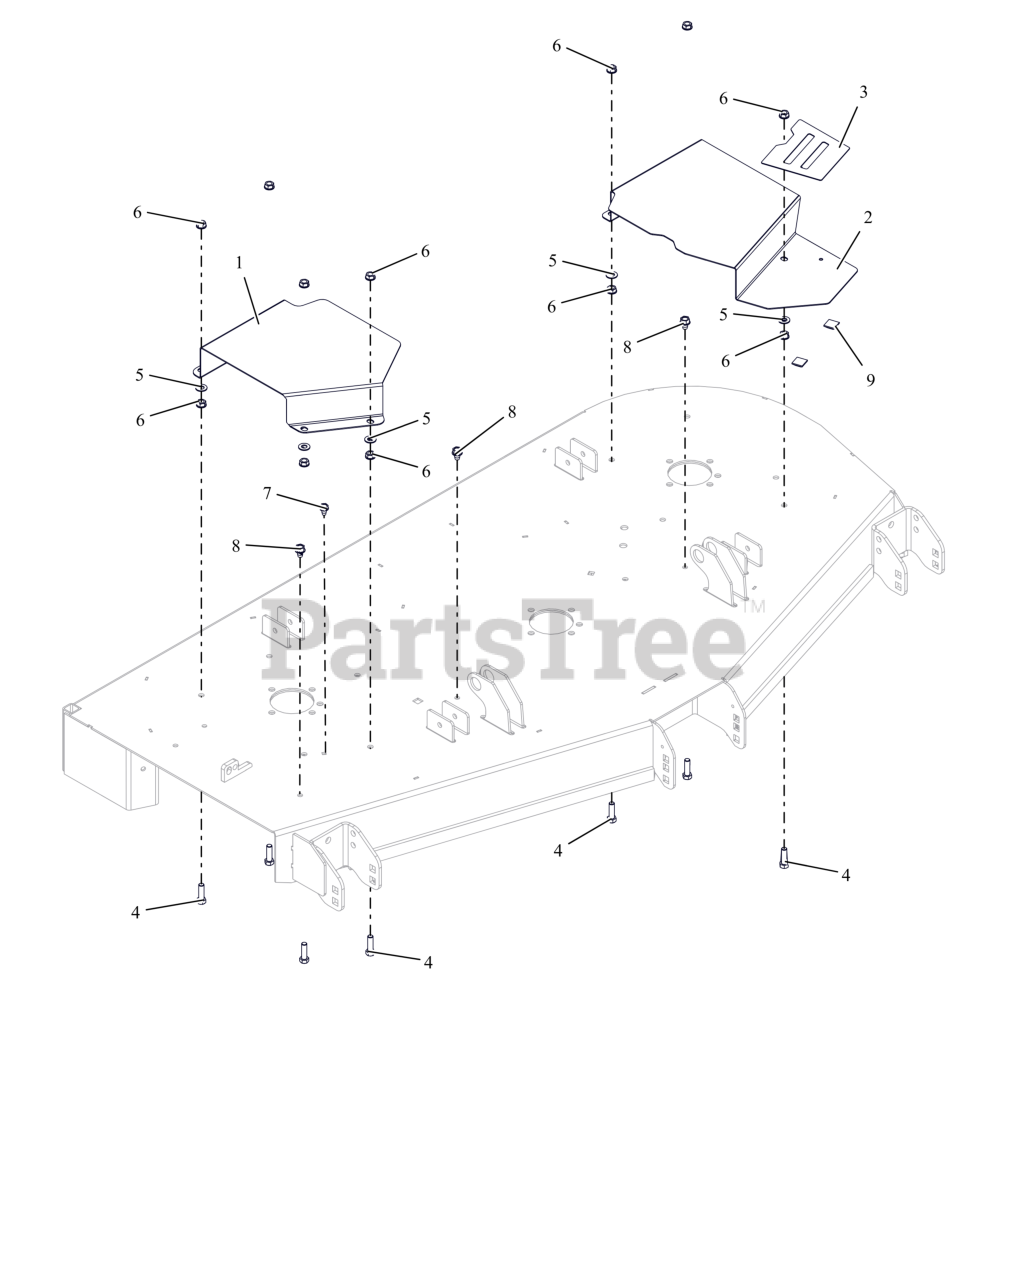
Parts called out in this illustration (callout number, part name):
1	COVER, BELT 52" & 60" RIGHT
2	COVER, BELT 60" LEFT
3	GRIP TAPE 52-60 BELT COVER
4	BLT, HEX .38-16X1.25 G5 ZCC
5	WSHR,FLT .406X.812X.065 ZCC
6	NUT, SPNLK-FLG .38-16 G5 ZCC
7	SCR,TAP .312-18X.50 HWH TR ZCC
8	SCR,TAP .375-16X.50 HWH TR ZCC
